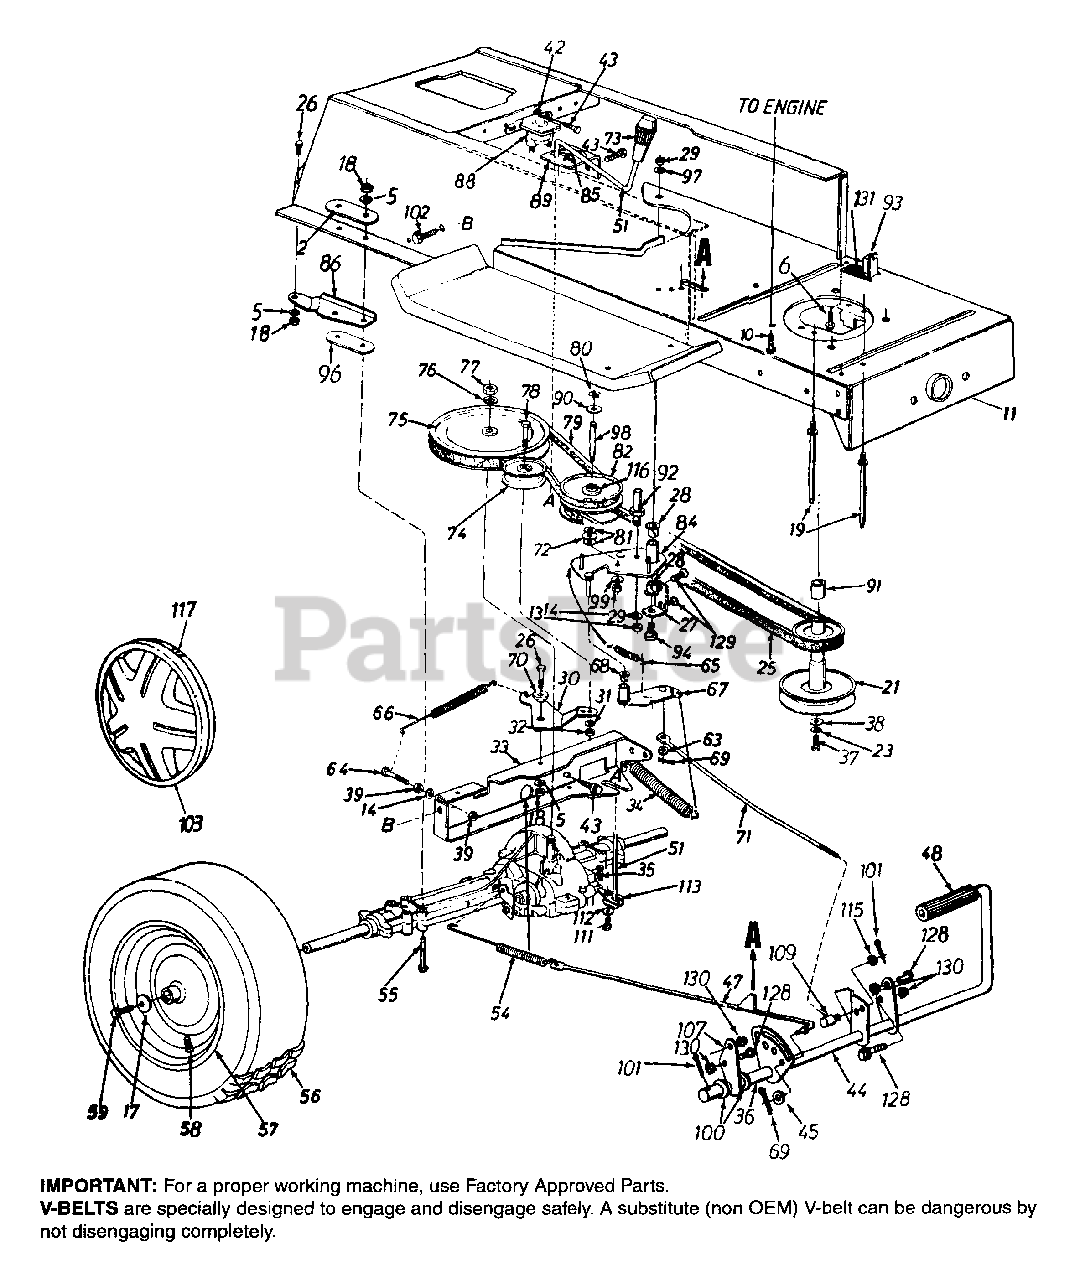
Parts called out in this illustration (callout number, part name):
5	L-Wash. 5/16" I.D.
6	Self-Tap Screw 1/4 x .50
10	Hex TT-Tap Scr. 3/8-16 x 1.5" Lg.
13	Hex Nut 1/4-20 Thd. (Gr. 5)
14	L-Wash. 1/4" I.D.
17	Bell-Wash. .345" I.D. x .88"
18	Hex Nut 5/16-18 Thd. (Gr. 5)
19	Belt Guard Stud 4.75" Lg.
21	Engine Pulley
23	L-Wash. 7/16" I.D.
25	Variable-Speed Belt
26	Hex Bolt 5/16-18 x .75" Lg.
27	Bearing Shaft Bracket Ass'y.
28	Flanged Nyliner Brg. 5/8" I.D. x .88" Lg.
29	Hex Nut 3/8-24 Thd.
31	L-Wash. 3/8" I.D.
32	Hex Nut 3/8-24 Thd.
35	Inter. Cotter Pin
36	Spacer .63" I.D.
37	Cap Screw 7/16-20 x 1.25
38	Flat Washer .450
39	Hex Nut 1/4-28 Thd.
42	Ext. L-Wash. 1/4" I.D.
43	Hex Wash. S-Tap Scr. 1/4-20 x .50" Lg.
47	Brake Rod Ass'y.
48	Foot Pad
51	Shift Lever Ass'y.
54	Ext. Spring .59" O.D. x 7.08"
55	Hex Bolt 5/16-16 x 3.5" Lg.
58	Air Valve
59	Hex Bolt 5/16-24 x .75" Lg.
63	Fl-Wash. .34" I.D. x .68" O.D.
64	Hex Bolt 1/4-28 x 1.25" Lg.
65	Ext. Spring
66	Ext. Spring .62" O.D. x 6.12"
68	Flanged Bearing
69	Cotter Pin 3/32" Dia.
70	Shoulder Spacer .27" Lg.
71	Speed Control Link
72	Truss Bearing .56 Dia. x 1.25"
73	Shift Knob
74	Fl-Idler Pulley 3.12" Dia.
75	"V" Pulley
76	Bell-Wash. .56" I.D. x 1.125"
77	Hex Jam Nut 5/16-18 Thd.
78	Hex Bolt 3/8-24 x 1.75" Lg.
79	Variable Speed Belt
80	Snap Ring .56" Dia.
81	Fl-Wash.
82	Variable Speed Pulley Ass'y.
90	Teflon Washer.565" I.D.
91	Spacer 1" I.D. x 1.25" Lg.
92	Belt Keeper 3" Lg.
93	Safety Switch (Clutch)
94	Shld. Bolt 3/8-24 x 3.12" Lg.
96	transaxle Spacer
97	Bell-Wash. .38" I.D. x .88"
98	Shaft .56" Dia. x 3.875" Lg.
99	Bell-Wash. .39" I.D. x 1.12"
100	Fl-Wash. .64" I.D. x .94"
101	Cotter Pin 1/8" Dia. x 1.25"
102	Hex Wash. Hd. Scr. 5/16-18 x .62"
103	Hub Cap (Gray)
111	Hex Bolt 1/4-28 x .50" Lg.
112	Bell-Wash. .265" I.D. x.75"
113	Shift Lever Link Ass'y.
115	Fl-Wash, .385" I.D. x .62"
116	Needle Brgs. (2 Req'd.)
117	Spring Clip
128	Hex Wash. TT-Tap Scr. 5/16-18 x .75"
129	Hex Wash. AB-Tap Scr. 5/16-18 x .75"
130	Hex Sems Nut 5/16-18 Thd.
131	Spring Switch
